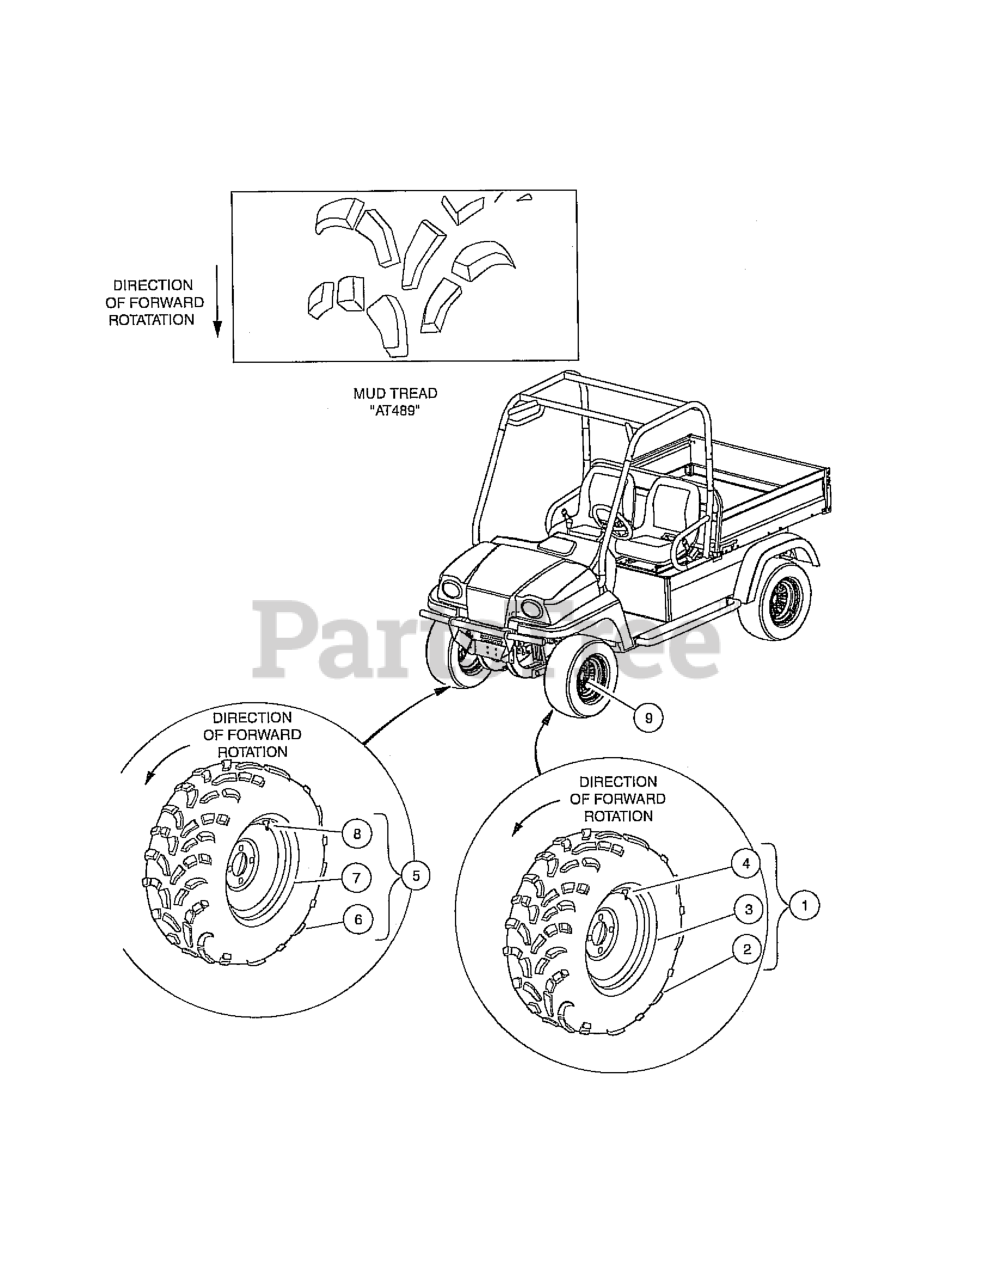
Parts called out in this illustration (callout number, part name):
1	Gray Tire Assembly, AT489 LH
2	TIRE, AT 489
3	Wheel, Indus Spider, Gray
5	Gray Tire Assembly, AT489 RH
6	TIRE, AT 489
7	Wheel, Indus Spider, Gray
9	NUT, LUG 1/2-20, SAE J 2283
